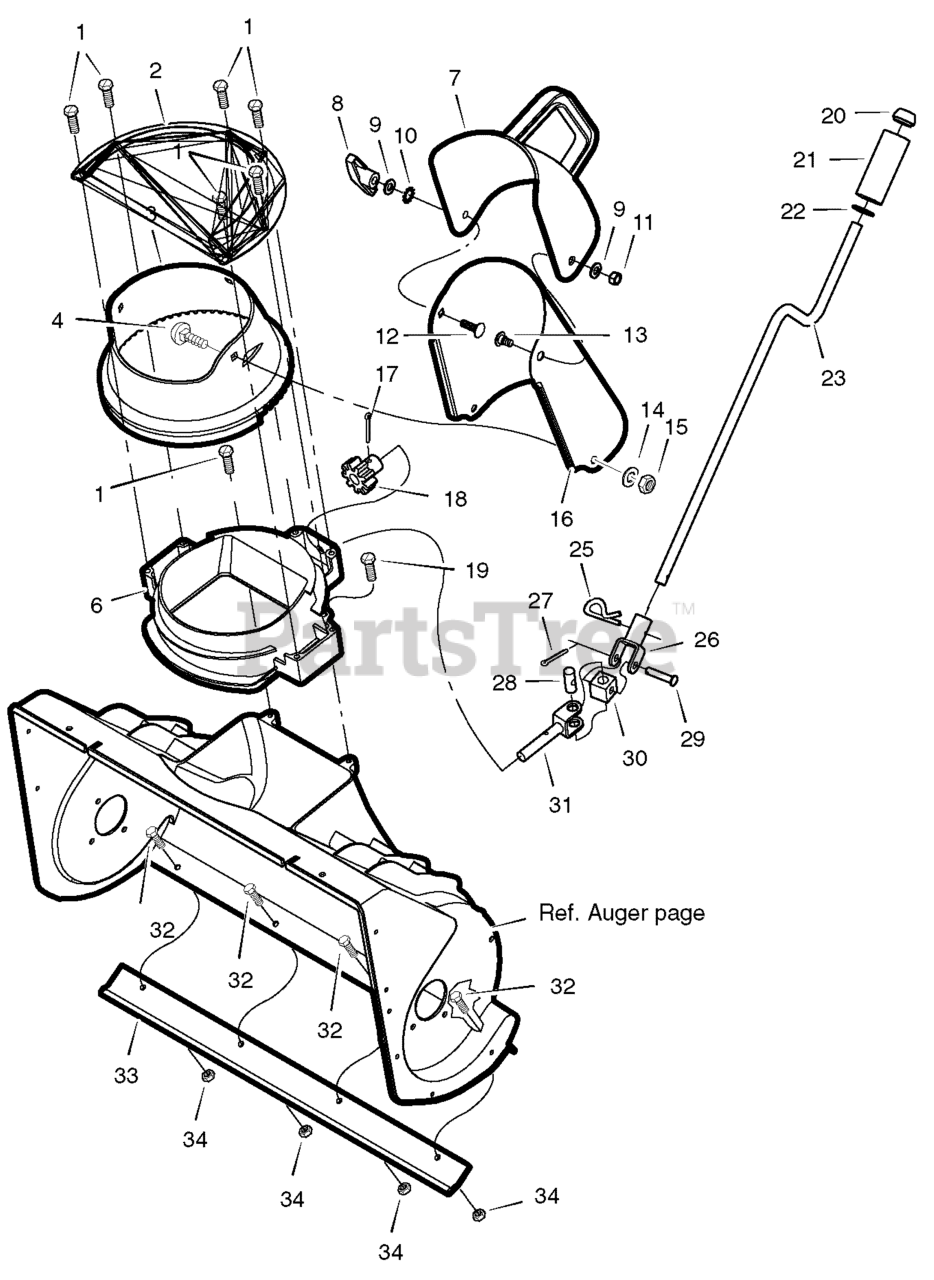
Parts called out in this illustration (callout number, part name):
1	Screw 1/4-14
2	Retainer, Chute Ring
3	Ring, Chute
4	Bolt, Carr 5/16-18x.75
6	Neck, Chute
7	Chute, 22" Upper
8	T-Knob
9	Washer
10	Lockwasher
11	Locknut 5/16-18
12	Bolt, Carr 5/16-18
13	Bolt, Upper Chute
14	Washer
15	Nut
16	Chute, Lower
17	Pin, Cotter
18	Gear, 9-Tooth
19	Screw, 1/4-14 x .75
20	Nut, Push
21	Knob, Sleeve
22	Washer
23	Crank, Chute
25	Pin, Hair
26	Yoke Assy, Adapter
27	Pin, Cotter
28	Pin, Universal Joint
29	Pin, Clevis
30	Housing, Universal
31	Rod, Lower Crank
32	Screw 1/4-20 x .75
33	Blade, Scraper
34	Locknut, Hex 1/4-20
